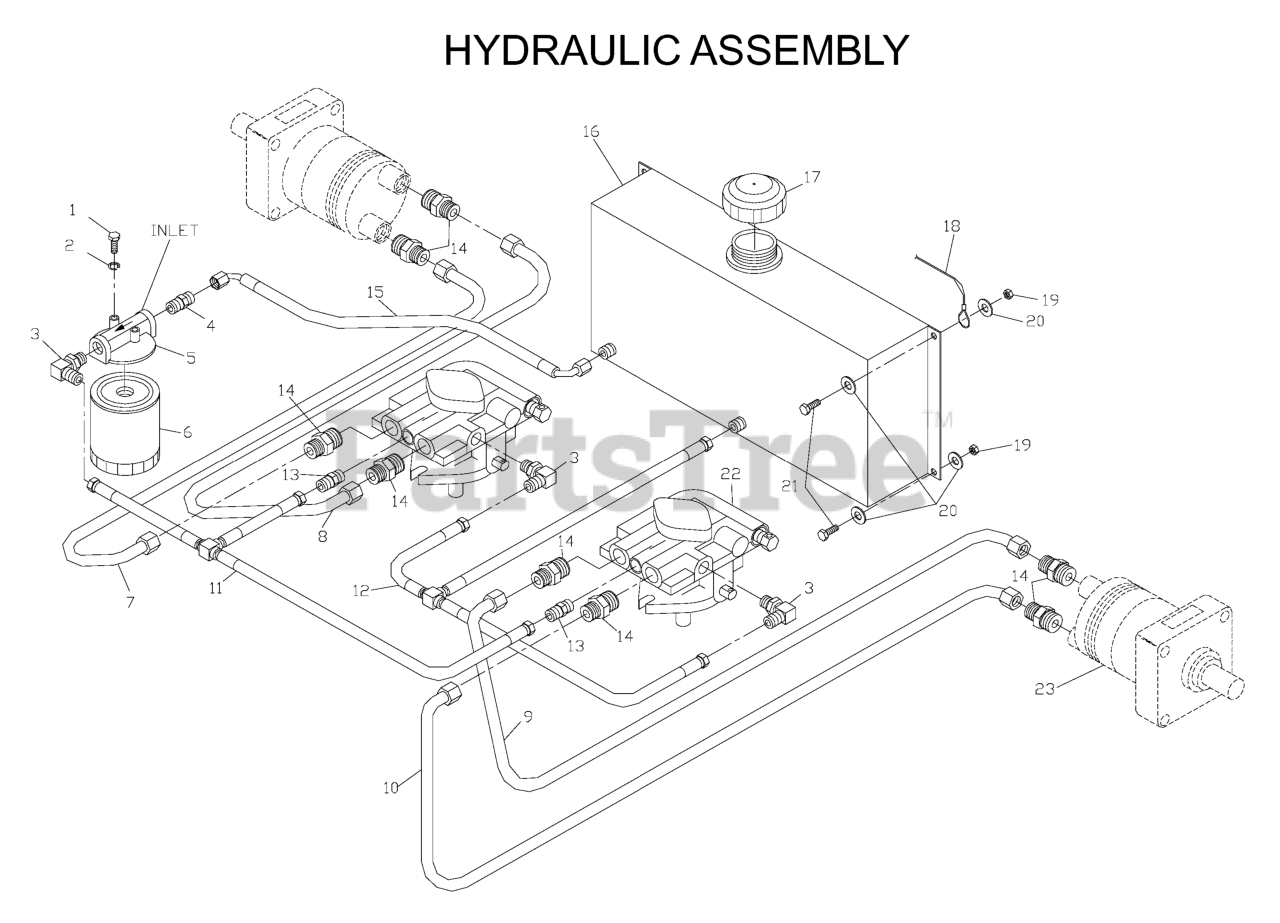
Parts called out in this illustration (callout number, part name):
1	HCS 1/4C X 5/8
2	LOCKWASHER 1/4"
3	ELBOW, F6801-6-6-0 90 DEGREE
4	STRAIGHT FITG
5	FILTER HEAD
6	HYDRAULIC OIL FILTER
7	OUTSIDE TUBE, RIGHT
8	INSIDE TUBE, RIGHT
9	INSIDE TUBE, LEFT
10	OUTSIDE TUBE, LEFT
11	SUCTION TEE ASSEMBLY
12	RETURN TEE ASSEMBLY
13	FITTING, STRAIGHT F6400-6-4-0
14	FITTING, STRAIGHT F6400-8-8-0
16	TANK, HYDRAULIC
17	HYDRAULIC CAP
18	SEAT LANYARD
19	NUT 1/4C CENTERLOCK
20	WASHER 1/4 FLAT
21	HCS 1/4 X 1
23	WHEEL MOTOR
